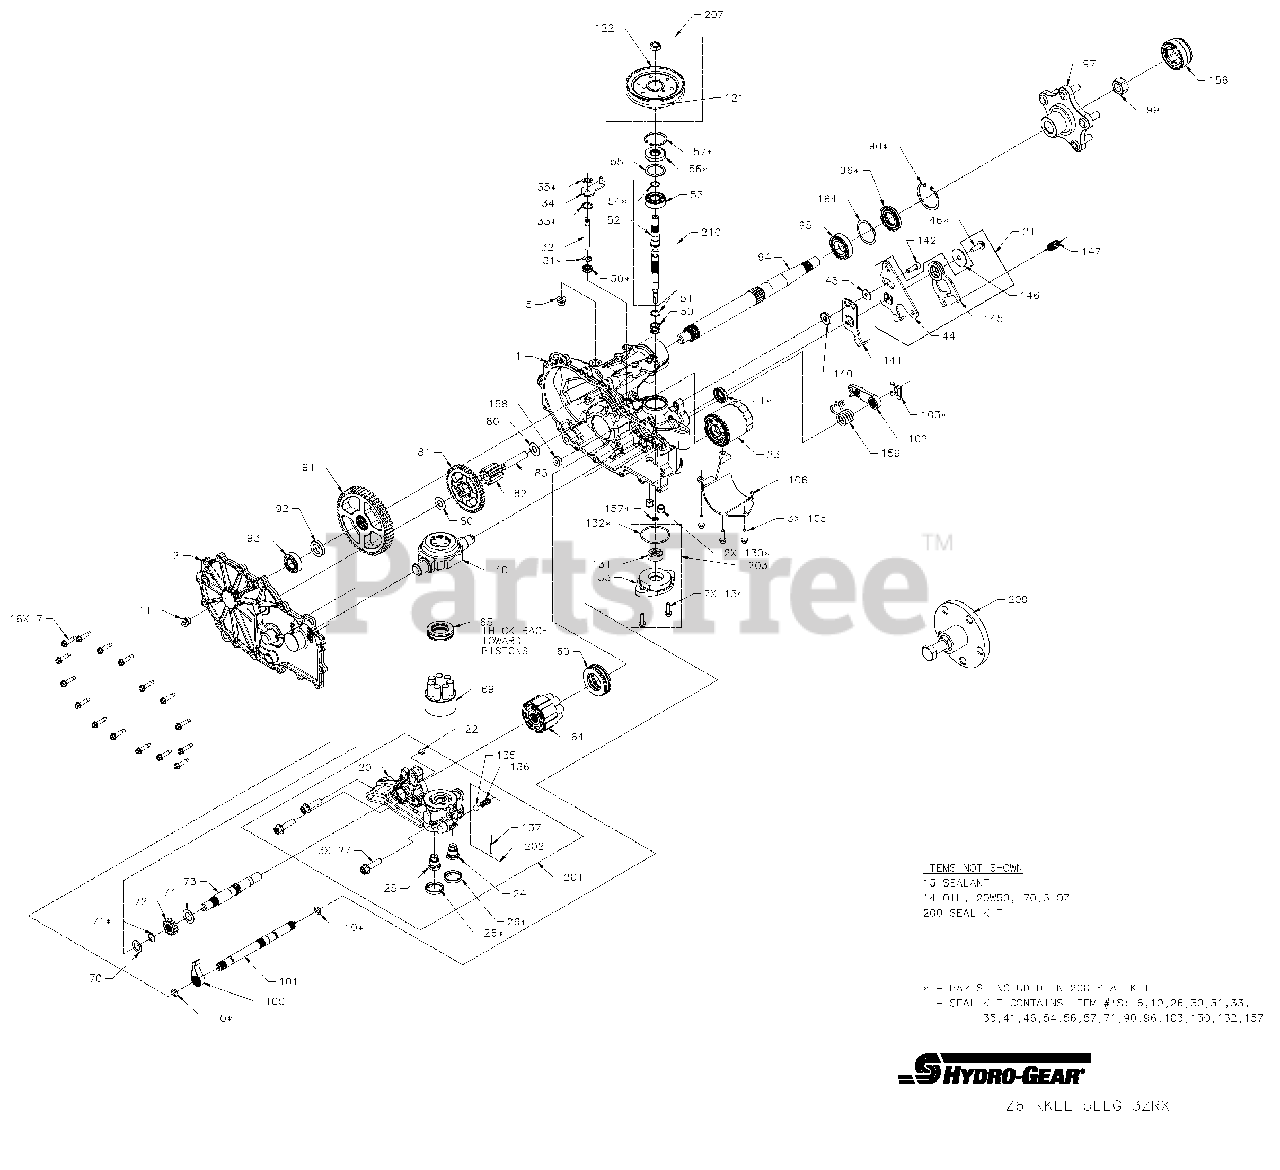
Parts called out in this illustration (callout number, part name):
13	SEALANT
23	FILTER, OIL
30	SEAL, LIP .375X.75X.25
31	RING, RET .375 EXTRNL
35	RING, RTNG .375 EXT
40	TRUNNION, SWASHPLATE
41	SEAL, LIP 12 X 32 X 7
46	TWHCS 5/16-24 X 1.00 (PATCH)
51	WASHER-FLAT .59 X .79 X .04
55	WASHER 1.23X1.56X.04
57	RING, RETAINING
69	KIT, BLOCK, 7 PISTON
80	WASHER .5X1.0X.03
99	NUT, HEX LOCK 3/4-16
122	NUT, HEX JAM 1/2-20 W/ PATCH
132	O-RING, -137, 0.103 X 2.050
146	WASHER, .343 X 1.500 X .062
147	SPRING, EXTENSION
